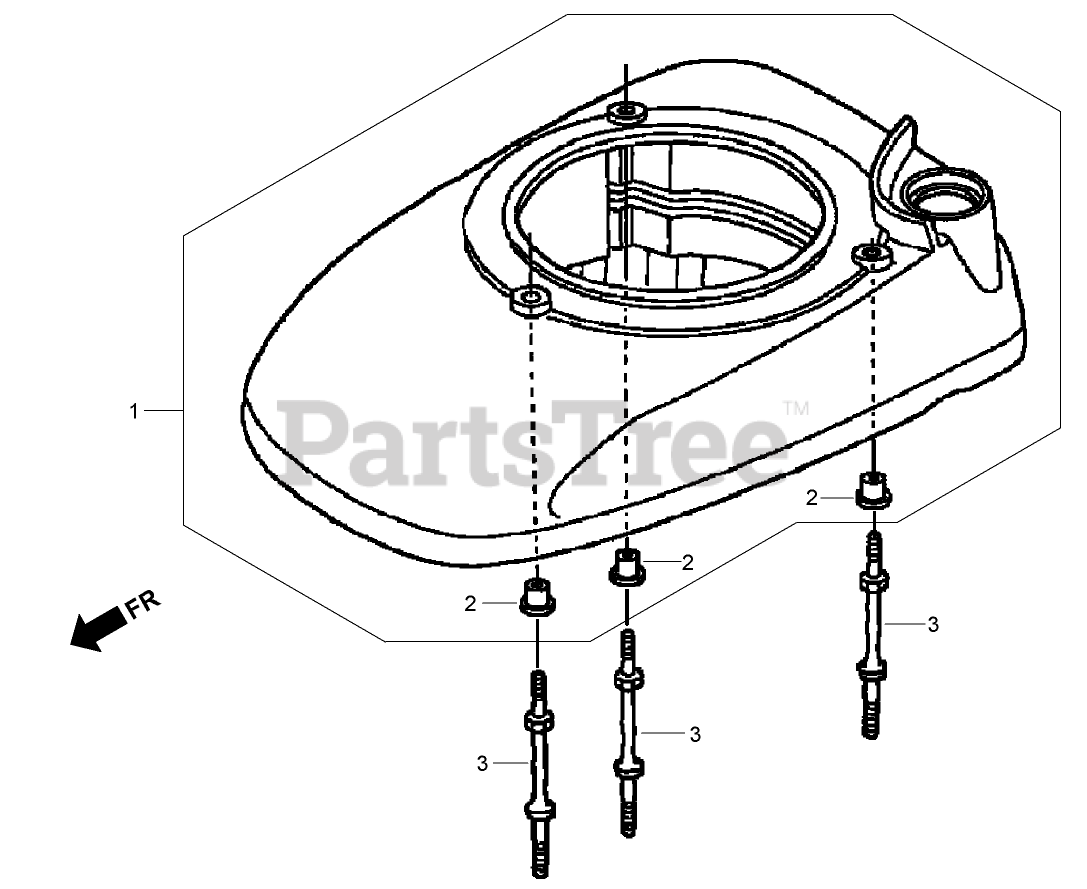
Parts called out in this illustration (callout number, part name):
1	COVER, FAN N H1 (BLACK)
2	COLLAR-COVER, FAN
3	BOLT-STUD (H=42.5MM)
